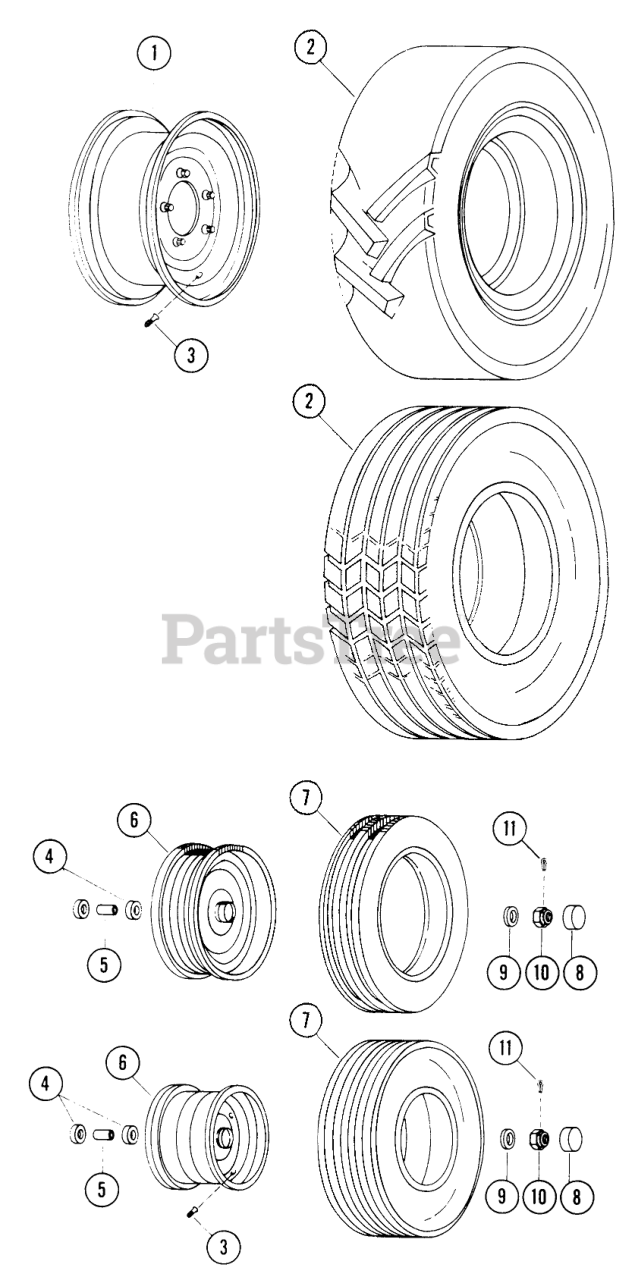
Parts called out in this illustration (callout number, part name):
1	Wheel, Regular Width (15 X 5.1 5 Bolt)
2	Tire, Regular Width Cleat (6.5-15 AS)
3	VALVE
4	Bearing
5	Spacer
6	Wheel, Shallow Rib (8 X 5 3/8)
7	Tire 18 X 850-8 Staight Rib
8	HUBCAP
9	Washer
10	Castel Nut
